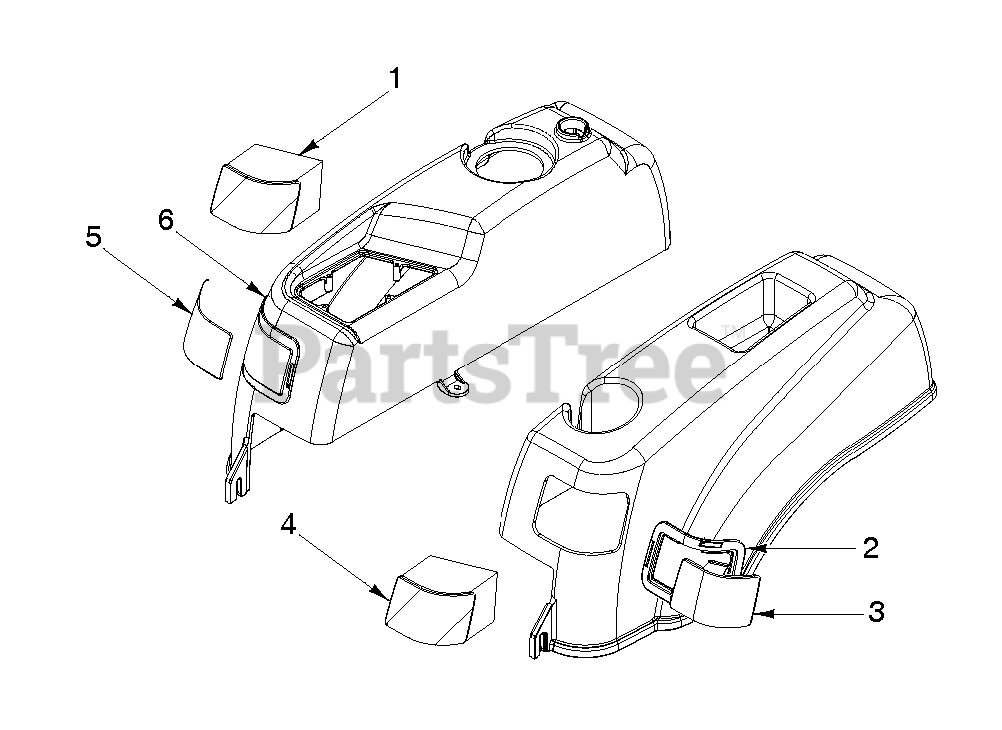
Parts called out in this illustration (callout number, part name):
1	REFLECTOR, HEADLIGHT RT
2	RING, TRIM LT BLK
3	LEFT HEADLIGHT LENS
4	REFLECTOR, LEFT HEAD LIGHT
5	RT HEADLIGHT LENS
6	RING, TRIM, RT-BLK
